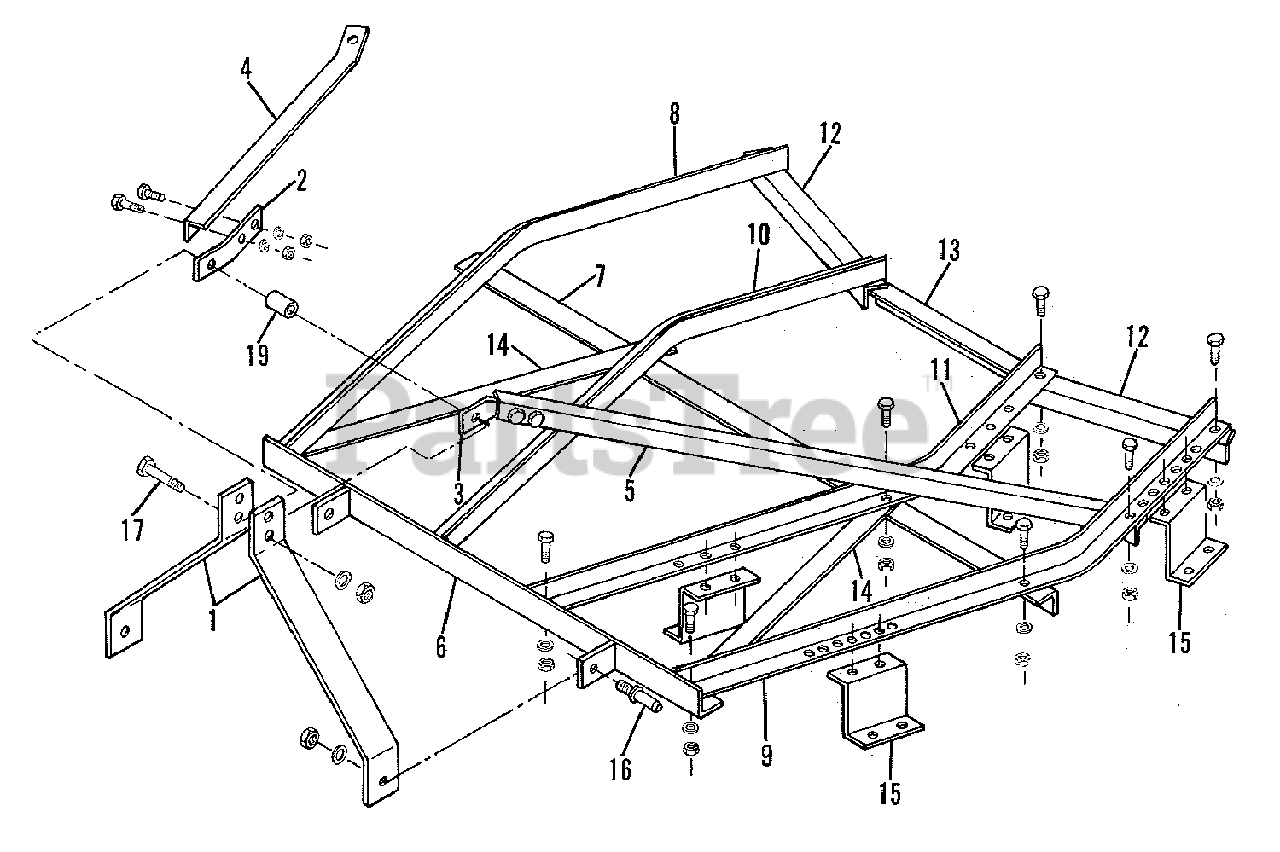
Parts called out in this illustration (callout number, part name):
1	FRAME, Tower
2	BRACE, Tower Frame, R.H.
2	CAPSCREW, 1/2NC x 1-1/2
2	LOCKWASHER, 1/2
3	BRACE, Tower Frame, L.H.
3	CAPSCREW, 1/2NC x 1-1/2
3	LOCKWSHER, 1/2
4	ARM, R.H. (For 6-1/2Ft. Sizes)
4	ARM, L.H. (For 5-1/2Ft. Sizes)
4	CAPSCREW, 1/2NC x 1-1/2
4	LOCKWASHER, 1/2
5	ARM, L.H. (For 6-1/2Ft. Sizes)
5	ARM, L.H. (For 5-1/2Ft. Sizes)
5	CAPSCREW, 1/2NC x 1-1/2
5	LOCKWASHER, 1/2
6	ANGLE, Front (For 6-1/2Ft. Sizes)
6	ANGLE, Front (For 5-1/2Ft. Sizes)
6	CAPSCREW, 1/2NC x 1-1/2
6	LOCKWASHER, 1/
7	ANGLE, Center (For 6-1/2Ft. Sizes)
7	ANGLE, Center (For 5-1/2Ft. Sizes)
7	CAPSCREW, 1/2NC x 1-1/2
7	LOCKWASHER, 1/
8	ANGLE, Outer R.H. (For 6-1/2 Ft. Sizes)
8	ANGLE, Outer R.H. (For 5-1/2 Ft. Sizes)
9	ANGLE, Outer L.H. (For 6-1/2 Ft. Sizes)
9	ANGLE, Outer L.H. (For 5-1/2 Ft. Sizes)
10	ANGLE, Inner R.H. (For 6-1/2 Ft. Sizes)
10	ANGLE, Inner R.H. (For 5-1/2 Ft. Sizes)
11	ANGLE, Inner L.H. (For 6-1/2 Ft. Sizes)
11	ANGLE, Inner L.H. (For 5-1/2 Ft. Sizes)
12	ANGLE, Outer R.H. & LH. (For 6-1/2 Ft. Sizes)
12	ANGLE, Outer R.H. & LH. (For 55-1/2 Ft. Sizes)
12	CAPSCREW, 1/2NC x 1-1/2
12	LOCKWASHER, 1/2
13	ANGLE, Center, Rear (For 6-1/2 Ft. Sizes)
13	ANGLE, Center, Rear (For 5-1/2 Ft. Sizes)
13	CAPSCREW, 1/2NC x 1-1/2
13	LOCKWASHER, 1/2
14	BRACE, Flat (For 6-1/2 Ft. Sizes Only)
15	HANGER, Disk Gang
15	CAPSCREW, 1/2NC x 1-1/2
15	LOCKWASHER, 1/2
16	PIN, Link (Cat. l)
16	LOCKWASHER, 7/8
17	PIN, Hitch, Upper
19	SPACER, Tower Frame
19	CAPSCREW, 5/8NC x 4
19	LOCKWASHER, 5/8
20	DECAL (Allis-Chalmers)
21	DECAL (44 Model Identification)
